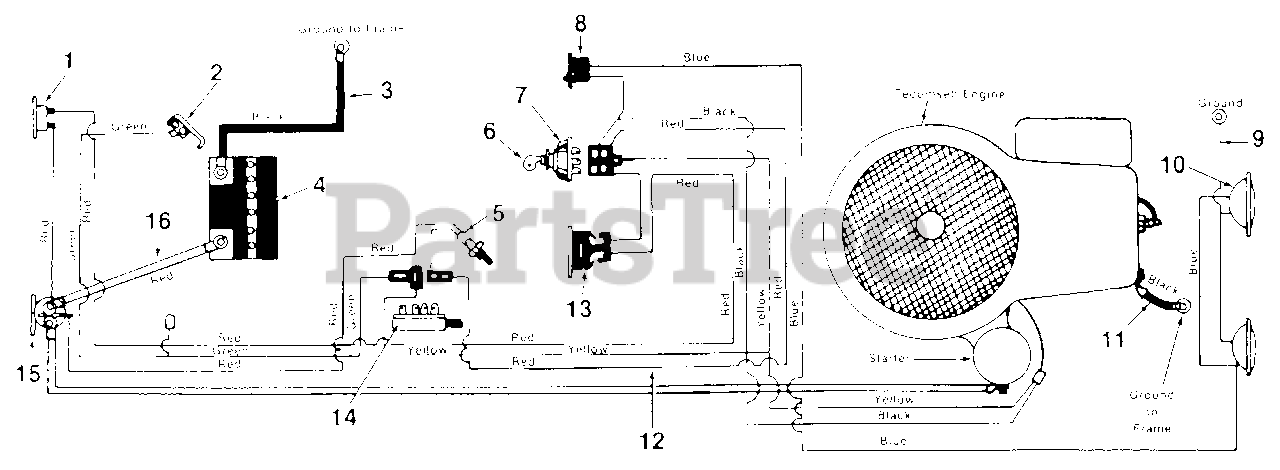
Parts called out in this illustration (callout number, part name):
1	Circuit Breaker
2	Spring Switch
3	Ground Wire 9.0" Lg.
4	12 Volt Battery
5	Safety Switch
6	Ignition Key
7	Ignition Switch
8	Light Switch
9	Ground Wire
10	Head Light
11	Ground Wire 7.25" Lg. (Black)
12	Wire Harness
13	Ammeter
14	Safety Switch
15	Solenoid
16	Electric Wire
